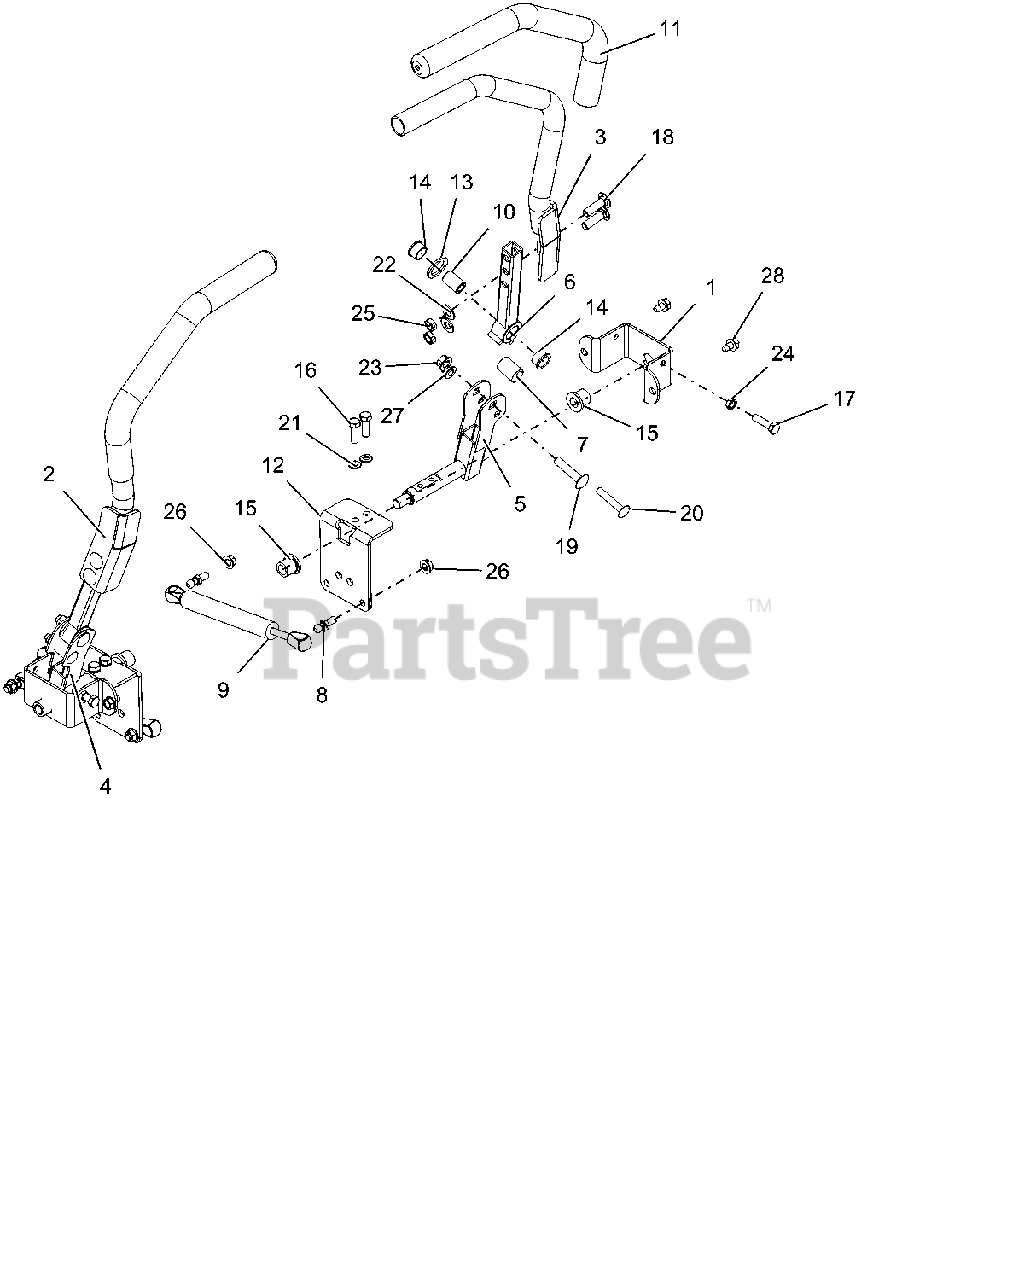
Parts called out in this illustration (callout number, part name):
1	BRKT, STEERING
2	WLDMT, STEERING HANDLE RH
3	WLDMT, STEERING HANDLE LH
4	WLDMT,STEERING ARM LOWER RIGHT
5	WLDMT,STEERING ARM LOWER LEFT
6	WLDMT, UPPER CONTROL ARM
7	BSHG,ECCEN .328X.750X1.01 PM
8	STUD- BALL
9	DAMPER, STABILUS
10	SPACER, .375X.625X.970 (PM)
11	GRIP, HANDLEBAR 15" FOAM
12	BRKT, STEERING
13	WASHER, FRICTION .875X1.25X.10
14	BSHG-FLG, .625X.75X.450X.875
15	BSHG-FLG .515X.750X.745X1.00NY
16	BLT-HEX .31-18X1.00 GR8 YWZC
17	@BLT-HEX .31-18X1.25 GR5 YWZC
18	BLT,RHSSN .38-16X1.25 G5 BFP
19	BLT,RHSSN .38-16X1.75 G5 BFP
20	BLT,RHSSN .31-18X1.75 G5 BFP
21	@WSHR-LK .31X.078 REG YWZC
22	@WSHR-FL-STL.406X.812X.065 YWZ
23	NUT-LK-CTR-FLG .38-16 YWZC
24	NUT- JAM .312-18 YWZC
25	@NUT-LK-CTR-JAM .375-16 YWZC
26	@NUT-LK-TOP-FLG .31-18 YWZC
27	@NUT-LK-NYL-FLG .31-18 YWZC
28	@SCR-TAP .31-18X.50 HWH TR YWZ
